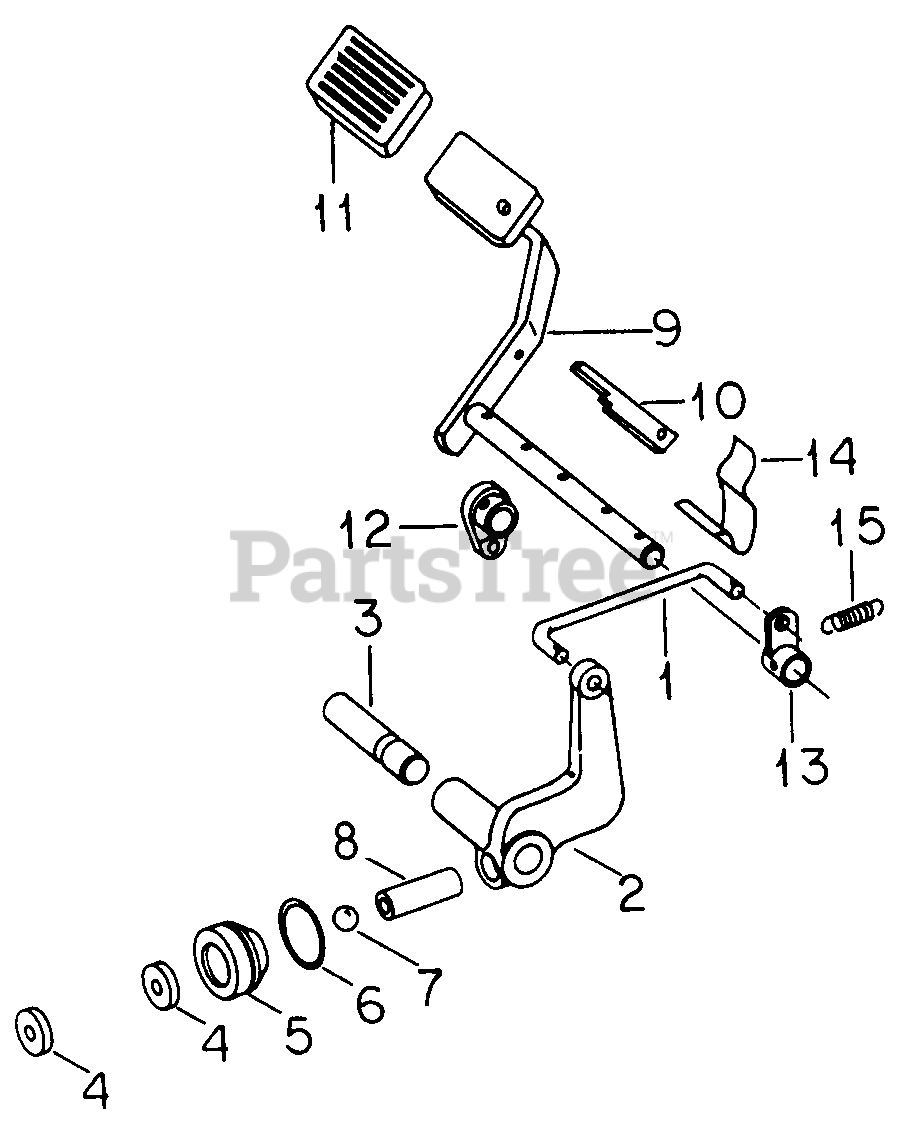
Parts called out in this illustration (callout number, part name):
1	Rod, Brake
2	Lever, Brake
3	Pin, Brake Pivot
4	Disc, Brake Lining
5	Retainer, Brake Lining
6	O-Ring, 1-3/16 X 3/32 Class 5
7	Ball, 9/16 Steel
8	Pin, Brake Push
9	Pedal Assy, Brake
10	Ratchet
11	Pad, Pedal
14	Spring, Switch Operating
15	Spring, Return
